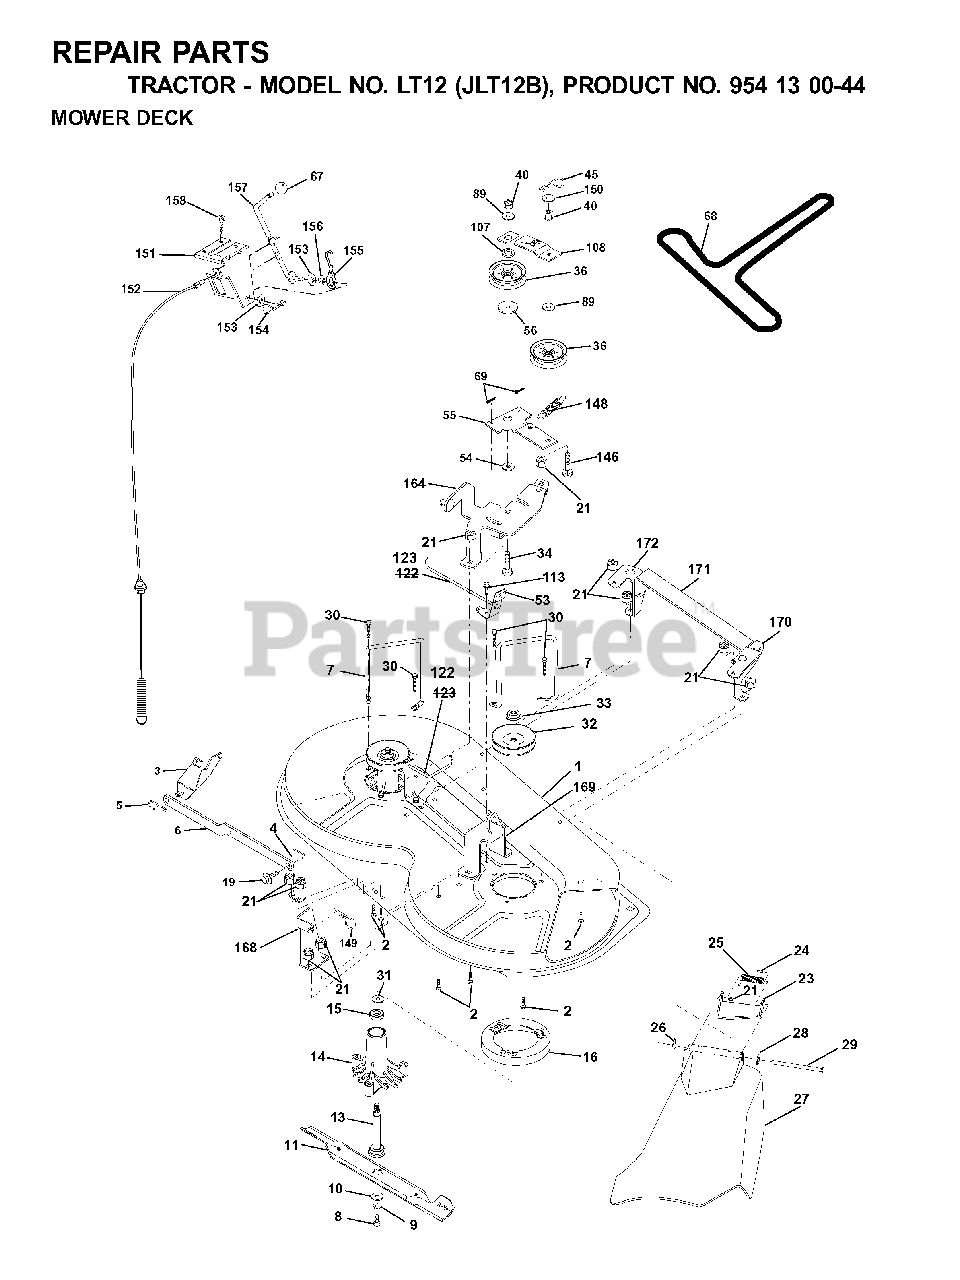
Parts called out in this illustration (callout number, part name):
2	BOLT
3	BRKT ASM SWAY BAR
5	RETAINER-SPRNG RB
6	REAR SUSP ARM
7	KEEPER LH
8	BLADE BOLT
9	LOCKWASHER
10	WASHER.BLADE
11	BLADE, HI-LIFT 36" PREMIUM
13	SHAFT ASM VENT
14	HSG MANDREL
16	STRIPPER, MWR ROUND
19	BOLT SHD 5/16-18
21	LOCKNUT
23	BRACKET ASM DEFLECTOR
24	CAP-SLEEVE LT
25	SPRING TORSION
26	NUT PUSH M
28	WASHER
29	HINGE ROD
30	SCREW THDROL ROLLING WASHER HD
31	WASHER
32	PULLEY, MANDREL
33	NUT
34	BOLT
36	FLAT IDLER PULLEY
40	LOCKNUT
45	RETAINER M
53	BRAKE ASSEMBLY
54	HARDENED WASHER
55	IDLER ARM
56	SPACER.RETAINER.MOWER
67	KNOB T (3/8 HOLE)
69	COTTER PIN
89	WASHER GT
107	SPACER.IDLER.ARM
108	STIFFENER.IDLER.ARM
146	BOLT, CARRIAGE IDLER
148	IDLER RETURN SPRING
149	SPRING.RETAINER.YELLOW.ZINC
150	WASHER PM
151	BRACKET, CLUTCH CABLE
153	WASHER FLAT 3/8"
154	SPRING RETAINER
155	SPRING RETENTION LEVER
156	SPACER CLUTCH CABLE
157	ROD CLUTCH CABLE 3/8"
158	SCREW LT
171	BRACE
